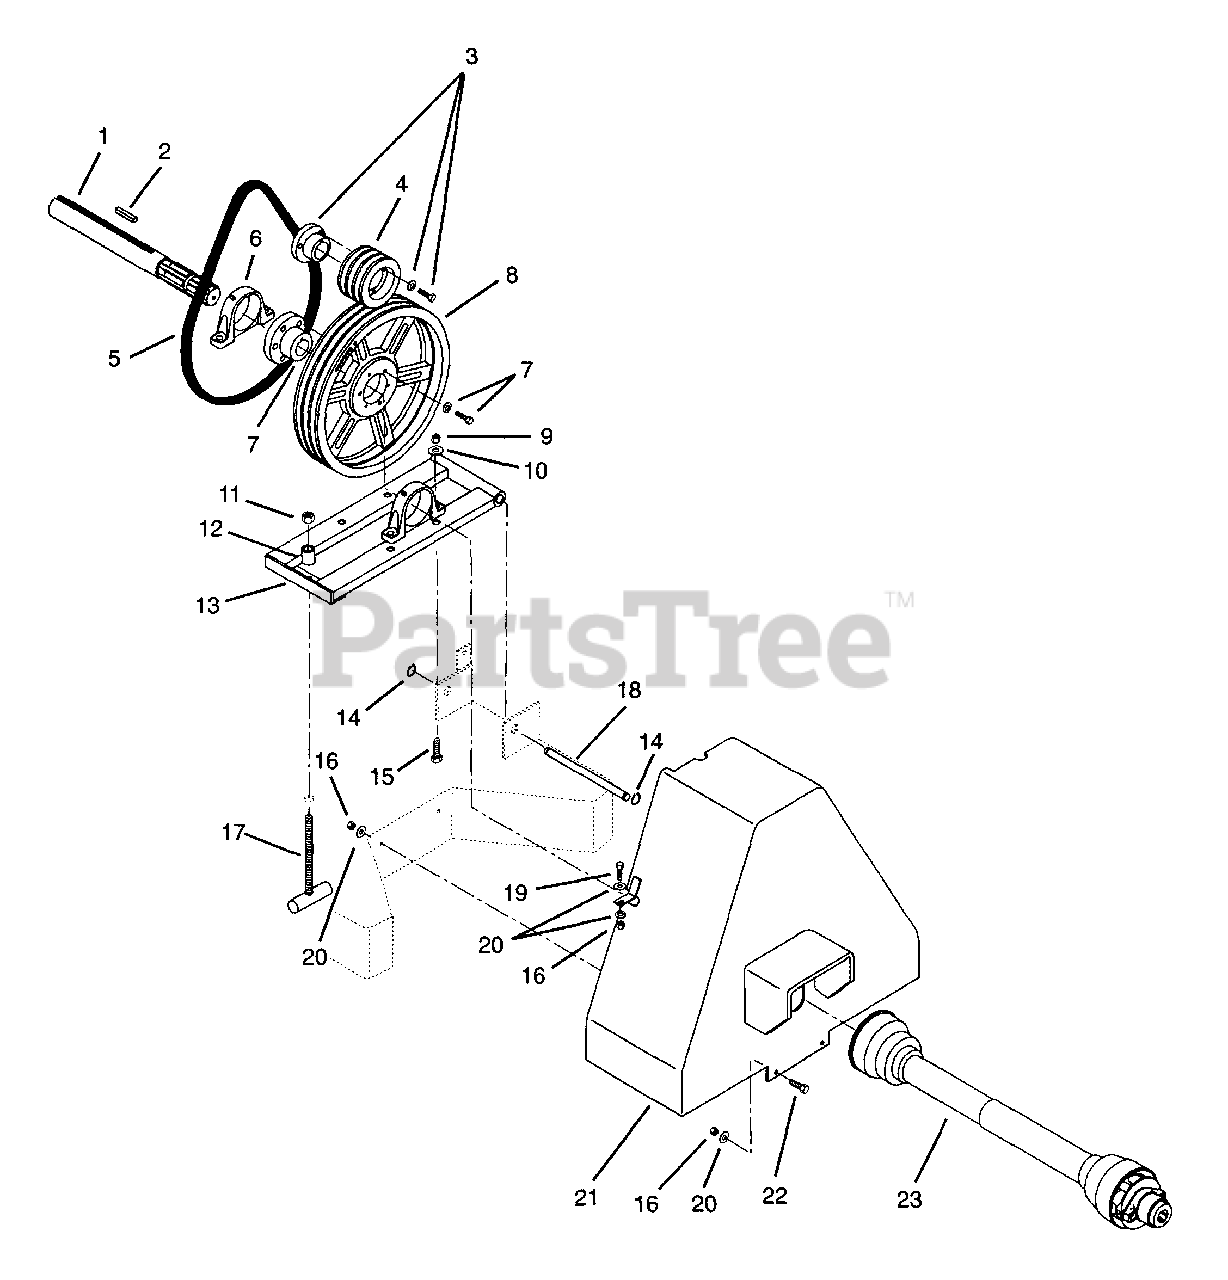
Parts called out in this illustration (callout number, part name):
1	PTO Jack Shaft
2	Key-Straight .38 x 2.0 x .38
3	Bushing with Hardware
5	V-Belt B54
6	Bearing Pillow
7	Bushing SK x 1 1/2 with Hardware
9	Nut-Locking-Center .50-13
10	Washer-Flat-Steel .531 x 1.06 x .095
11	Nut-Locking-Center .62-11
12	Adjuster Spacer
13	Swing Arm Weldment
14	Ring-Retaining-External 1.00 x .042
15	Bolt-Hex .50-13 x 2.75 Grade 5
16	Nut-Locking-Center .31-18
17	Threaded T Handle
18	Pin-Swing Arm
19	Bolt-Hex .31-18 x 1.00 Grade 5
20	Washer-Flat-Steel .38 x .875 x .083
21	Belt Guard Weldment
22	Bolt-Hex .31-18 x .75 Grade 5
